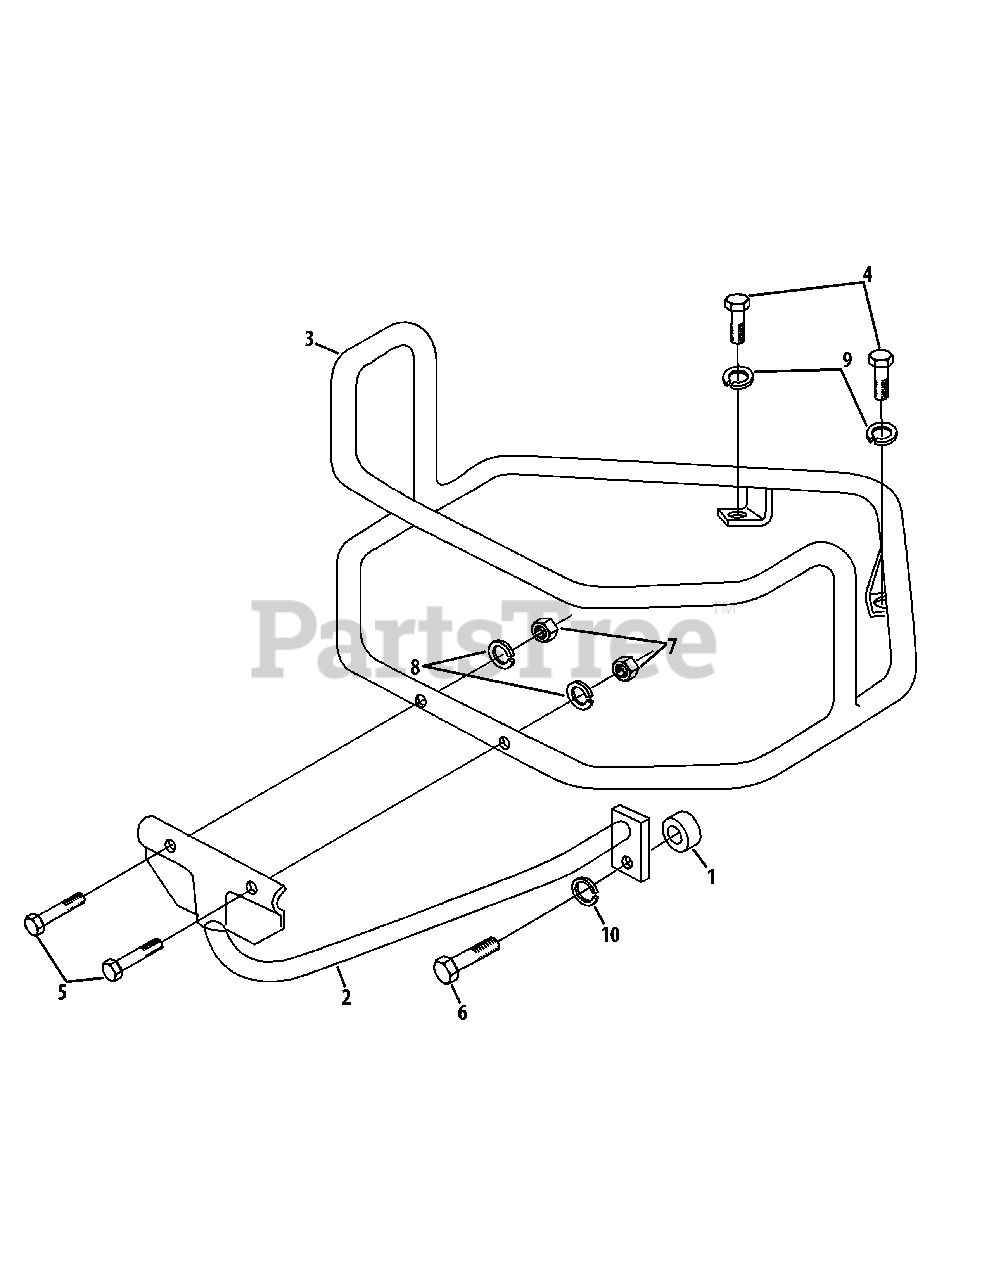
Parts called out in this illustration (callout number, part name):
1	Spacer, 10 x 546 x 5
2	Bottom Bumper Brace
3	Bumper Guard
4	Hex Screw, 3/8"-16 x 100
5	Hex Screw, 5/16"-18 x 150
6	Hex Screw, 1/2"-13 x 150
7	Hex Nut, 5/16"-18
8	Lock Washer, 5/16"
9	Lock Washer, 3/8"
10	Lock Washer, 1/2"
